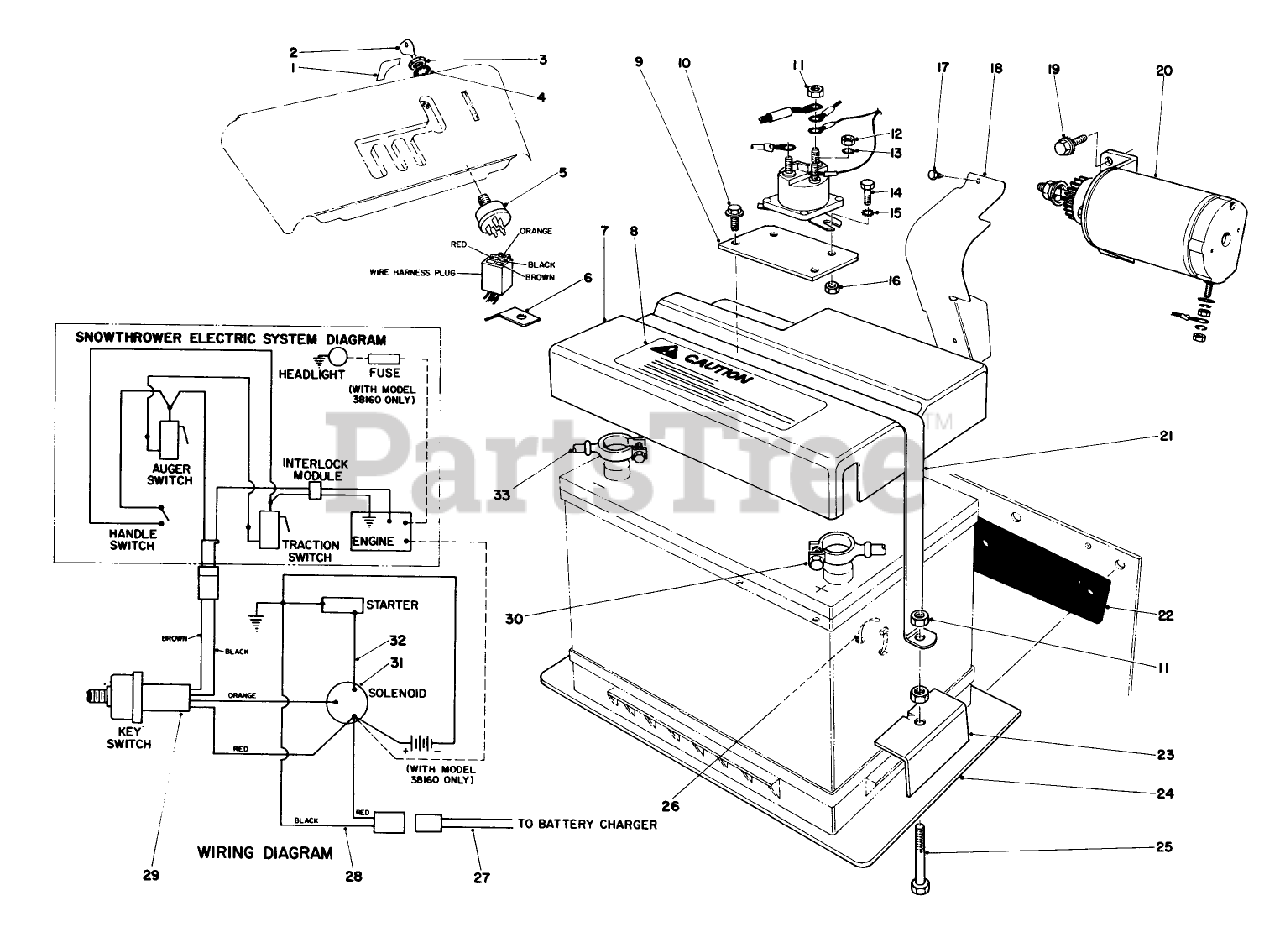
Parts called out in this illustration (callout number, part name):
3	NUT-HH
4	WASHER-LOCK
10	SCREW-HWH
11	NUT-HEX
12	NUT-HEX
13	WASHER-LOCK, INT
14	SCREW-HH
15	WASHER-LOCK/EXT
16	NUT-LOCK, NI
18	BRIGGS 280265
19	5/16-18X3/4 HX HD SEM
20	Starter Motor Pinion Assy.
25	SCREW-HH
26	TIE-CABLE
27	MALE WIRE ASM
30	BATT-SOLENOID CABLE
31	SOLENOID
